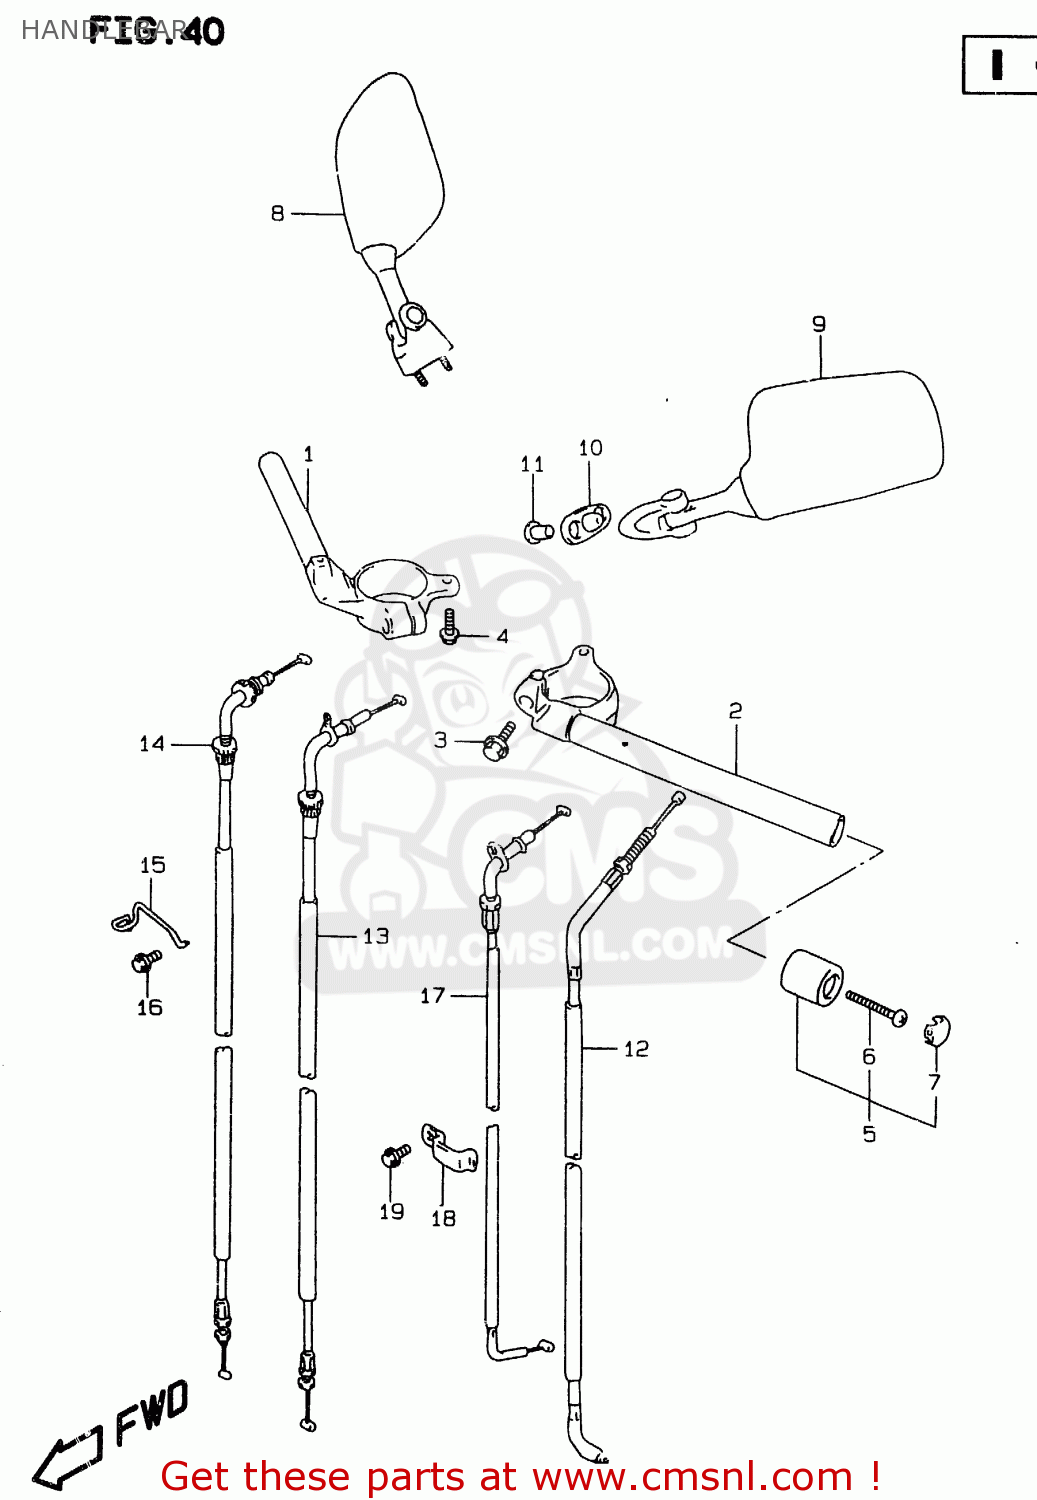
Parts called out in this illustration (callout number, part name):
1	HANDLEBAR,R
2	HANDLEBAR,L
3	BOLT
4	BOLT(8X30)
5	BALANCER SET,HANDLEBAR
6	SCREW
7	CAP,BALANCER
8	MIRROR ASSY,RR VIEW,R
9	MIRROR ASSY,RR VIEW,L
10	CUSHION,RR VIEW MIRRORR
11	NUT,RR VIEW MIRROR
12	CABLE ASSY,CLUTCH
13	CABLE ASSY,THROTTLE NO.1
14	CABLE ASSY,THROTTLE NO.2
15	GUIDE,THROTTLE CABLE
16	BOLT
17	CABLE,STARTER
18	CLAMP
19	BOLT
